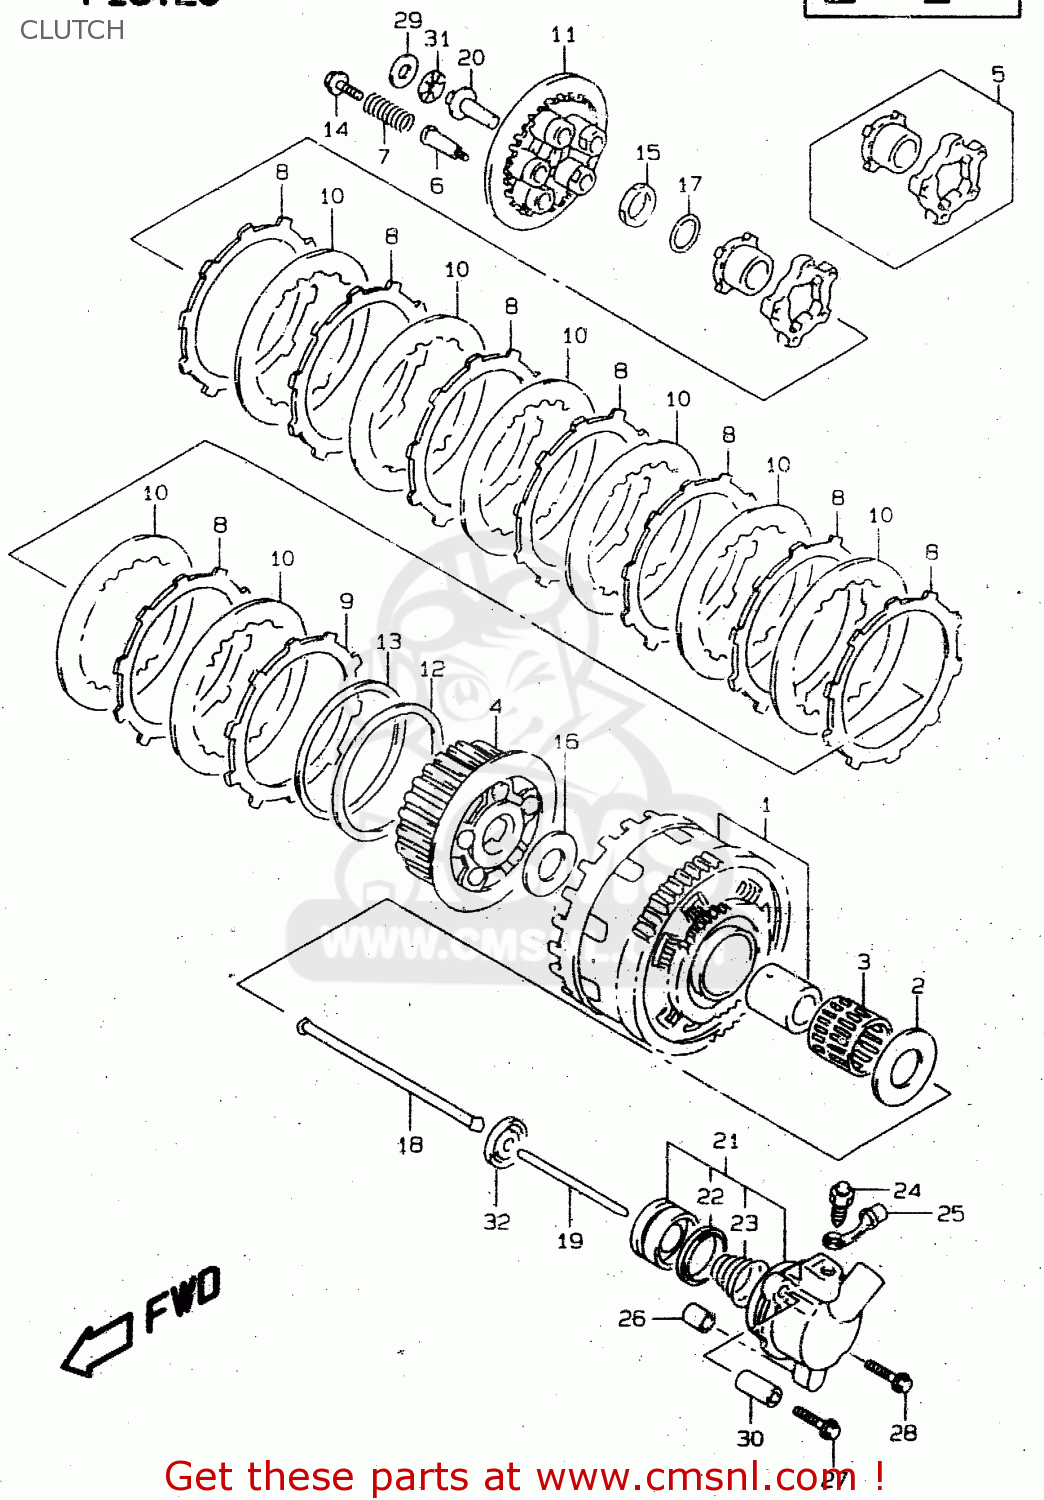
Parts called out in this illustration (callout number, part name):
1	GEAR ASSY,PRI DRIVEN
2	WASHER(25X54X2.5)
3	BEARING(35X40X35.8)
4	HUB,CLUTCH SLEEVE
5	CAM SET,CLUTCH
6	BOLT,SPRING SUPPORT
7	SPRING,CLUTCH
8	PLATE,CLUTCH DRIVE (NAS)
9	PLATE,CLUTCH DRIVE NO (NAS)
10	PLATE,CLUTCH DRIVEN (NAS)
11	DISC,CLUTCH PRESSURE
12	SEAT,WAVE WASHER
13	WASHER,CLUTCH PLATE WAVE
14	BOLT,CLUTCH SPRING
15	NUT
16	WASHER(25X50X2.5)
17	WASHER
18	ROD,CLUTCH PUSH,R
19	ROD,CLUTCH PUSH,L
20	PIECE,CLUTCH PUSH
21	CYLINDER,CLUTCH RELEASE
22	CUP
23	SPRING
24	BLEEDER
25	CAP,BLEEDER
26	PIN
27	BOLT
28	BOLT
29	WASHER(15.5X28X1)
30	SPACER(6.2X12X50)
31	BEARING(15X28X2)
32	SEAL,OIL(6X34X5.5)
